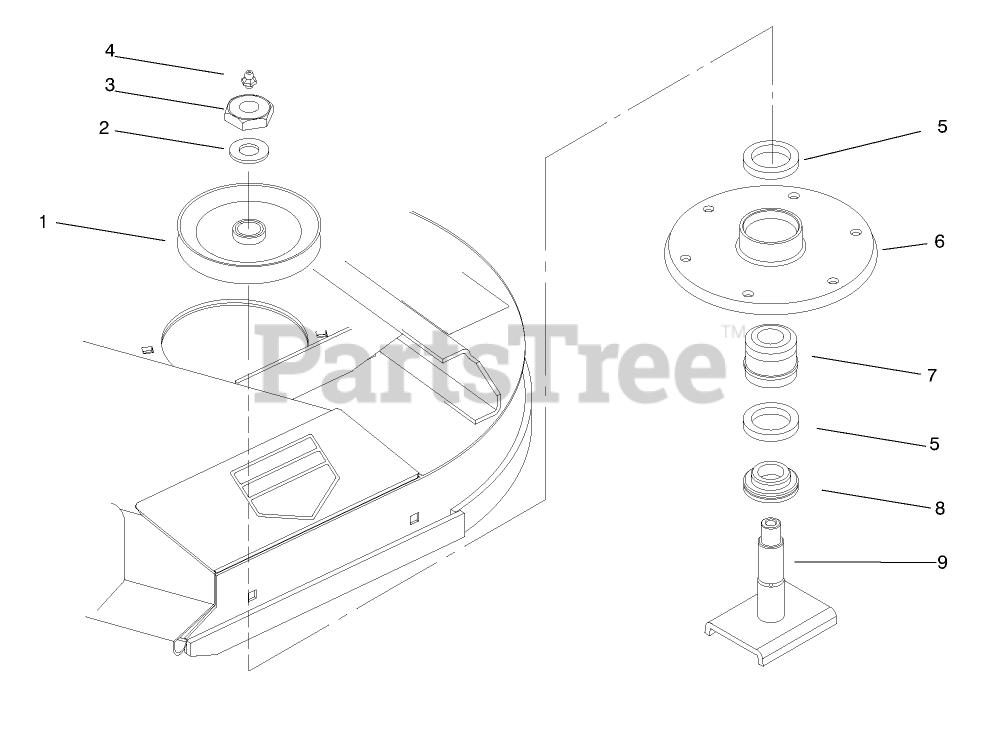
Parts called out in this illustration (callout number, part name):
1	PULLEY AND HUB ASM
2	WASHER
3	NUT-HEX
4	FITTING-GREASE
5	SEAL-OIL
6	HOUSING-SPINDLE
7	BEARING ASM
8	SHAFT
9	SPACER
